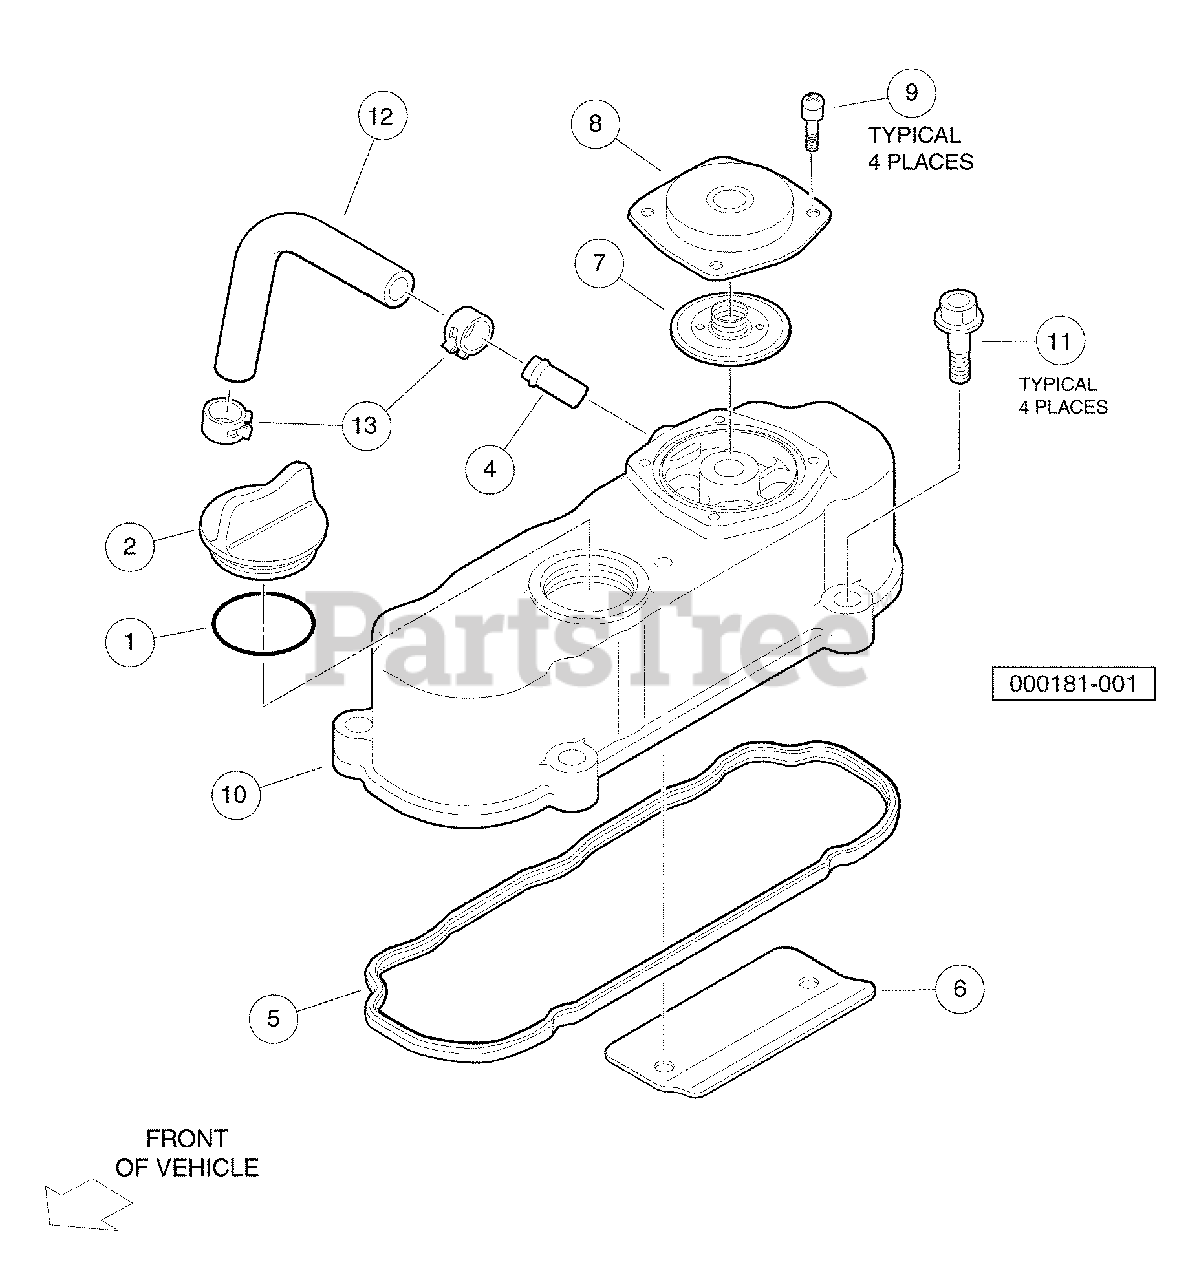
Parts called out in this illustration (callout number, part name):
1	O Ring, 30 X 36
2	Plug, Oil Filler
3	Assembly, Cylinder Head Cover
4	Pipe, Water Return, D722
5	Gasket, Cylinder Head Cover
6	Shield, Breather
7	Valve, Breather
8	Cover, Breather
9	Screw, Breather
10	Cover, Cylinder Head
11	Bolt, Cylinder Head Cover
12	Tube, Breather.
13	Clamp, Breather Tube
